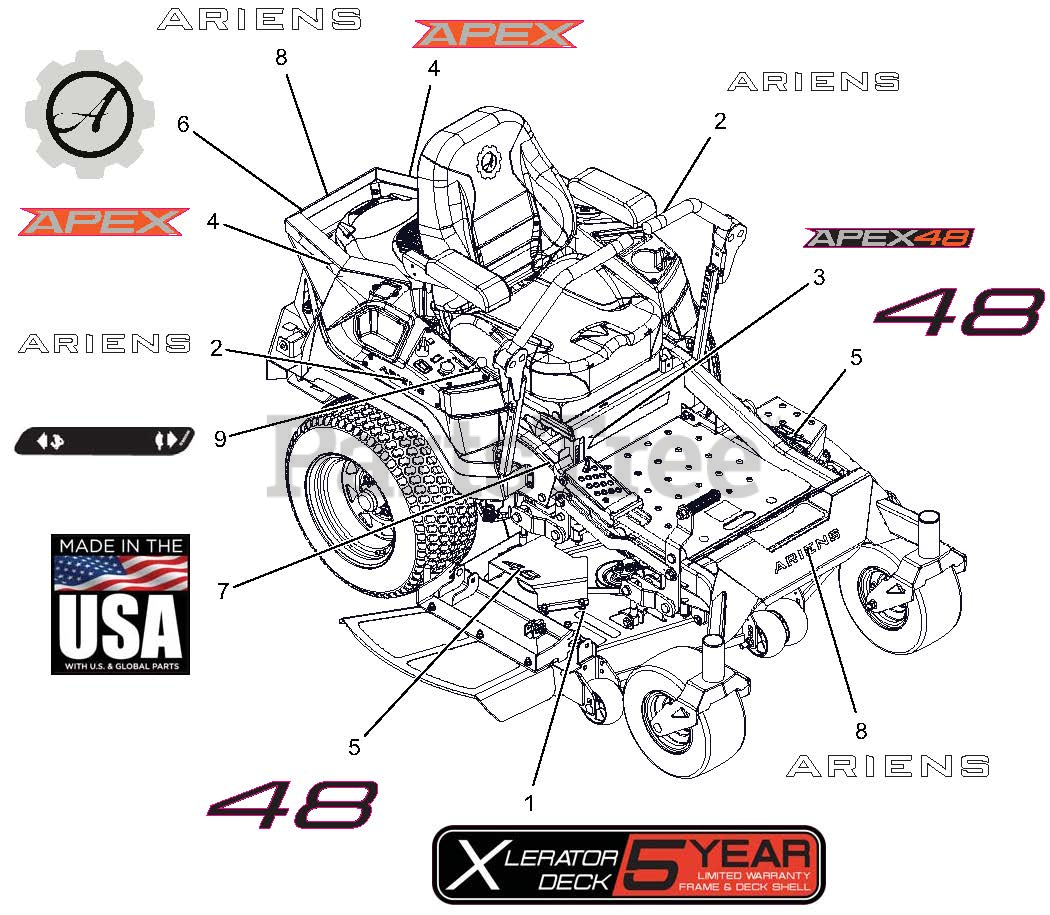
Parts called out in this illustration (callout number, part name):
1	DECAL-ARIENS, DECK 5 YEAR
2	DECAL, ARIENS (6.50")
3	DECAL, 48" APEX KICKPLATE
4	DECAL, APEX FENDER
5	DECAL, BLACK 48
6	DECAL, ARIENS-GEAR BADGE -THK
7	DECAL, MADE IN USA
8	DECAL - ARIENS 9.625"
9	DECAL, DASH DECAL
